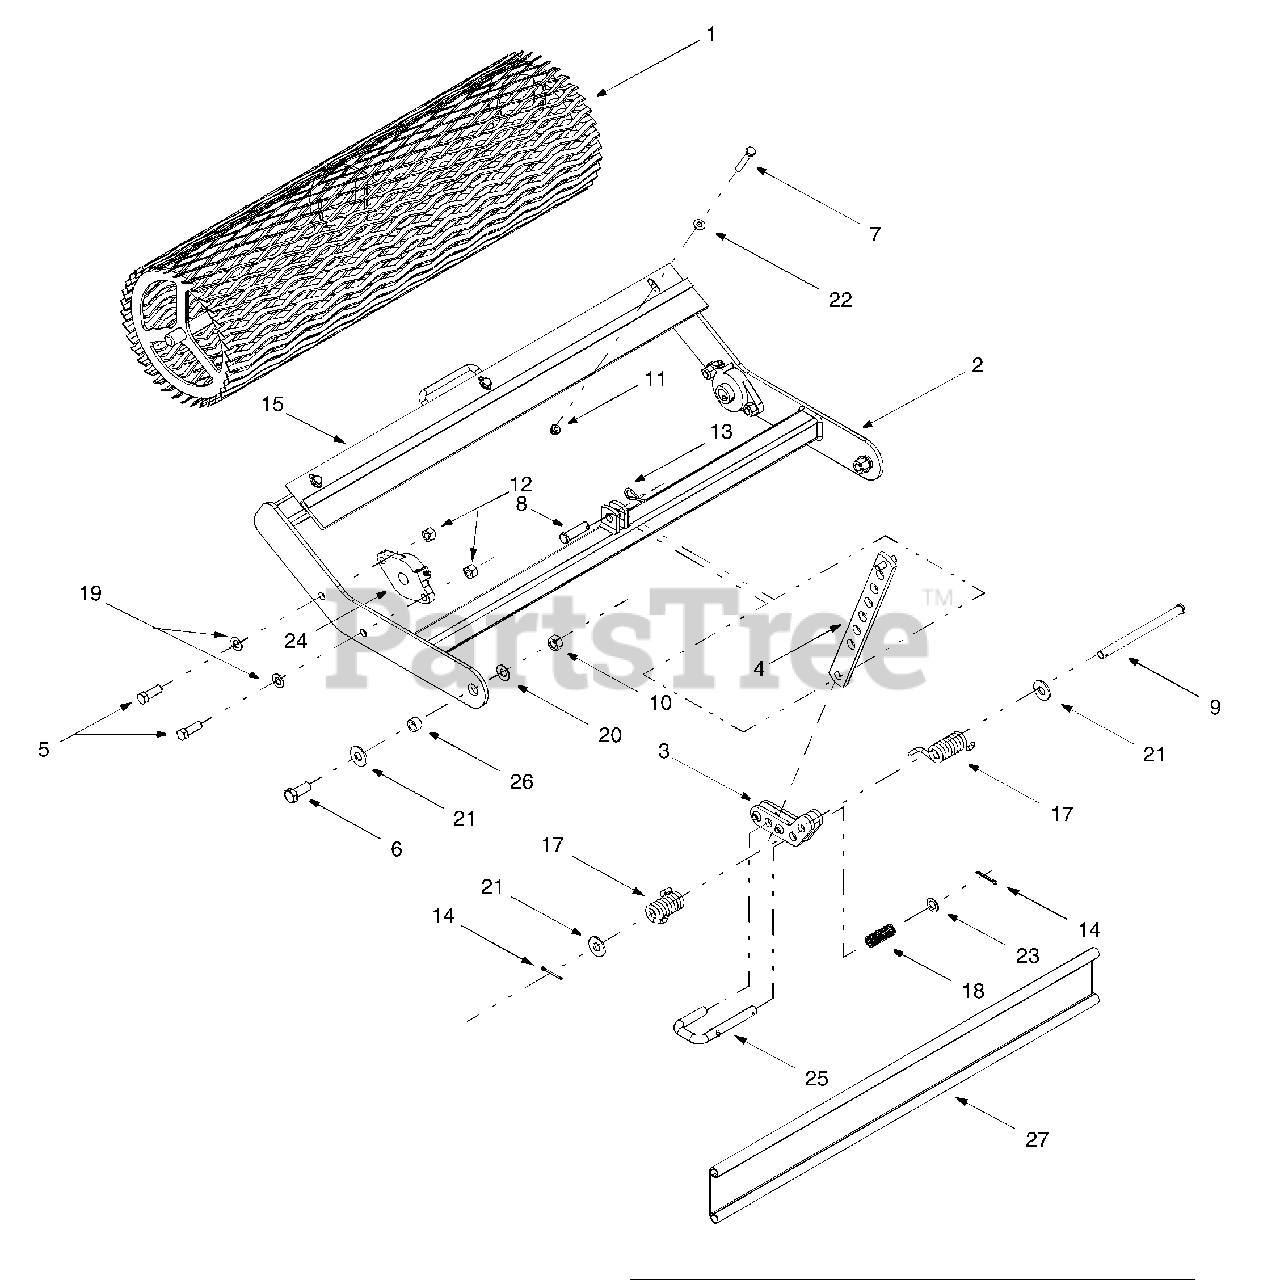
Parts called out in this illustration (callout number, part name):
6	Hex Cap Screw, 1/2-13 x 1.25
7	Hex Cap Screw, 5/16-18 x 2.0
8	Clevis Pin, .50 x 1.59
9	Clevis Pin, .50 x 6.5
10	Hex Nut, 1/2-13
11	Hex Lock Nut, 5/16-18
12	Hex Lock Nut, 7/16-20
13	Internal Cotter Pin
14	Cotter Pin, 1/8 x 1.25
15	30-inch Roller Brush
17	LH Torsion Spring
18	Compression Spring, .57 x 2.09
19	Flat Washer, .474 x .879 x .064
20	Belleville Washer
21	Flat Washer, .344 x .688 x .065
22	Flat Washer, .536 x 1.262 x .101
23	Flat Washer, .50 x .875 x .060
24	Flange Bearing, .75
25	Roller Locking Rod
26	Spacer, .51 x .75 x .44
